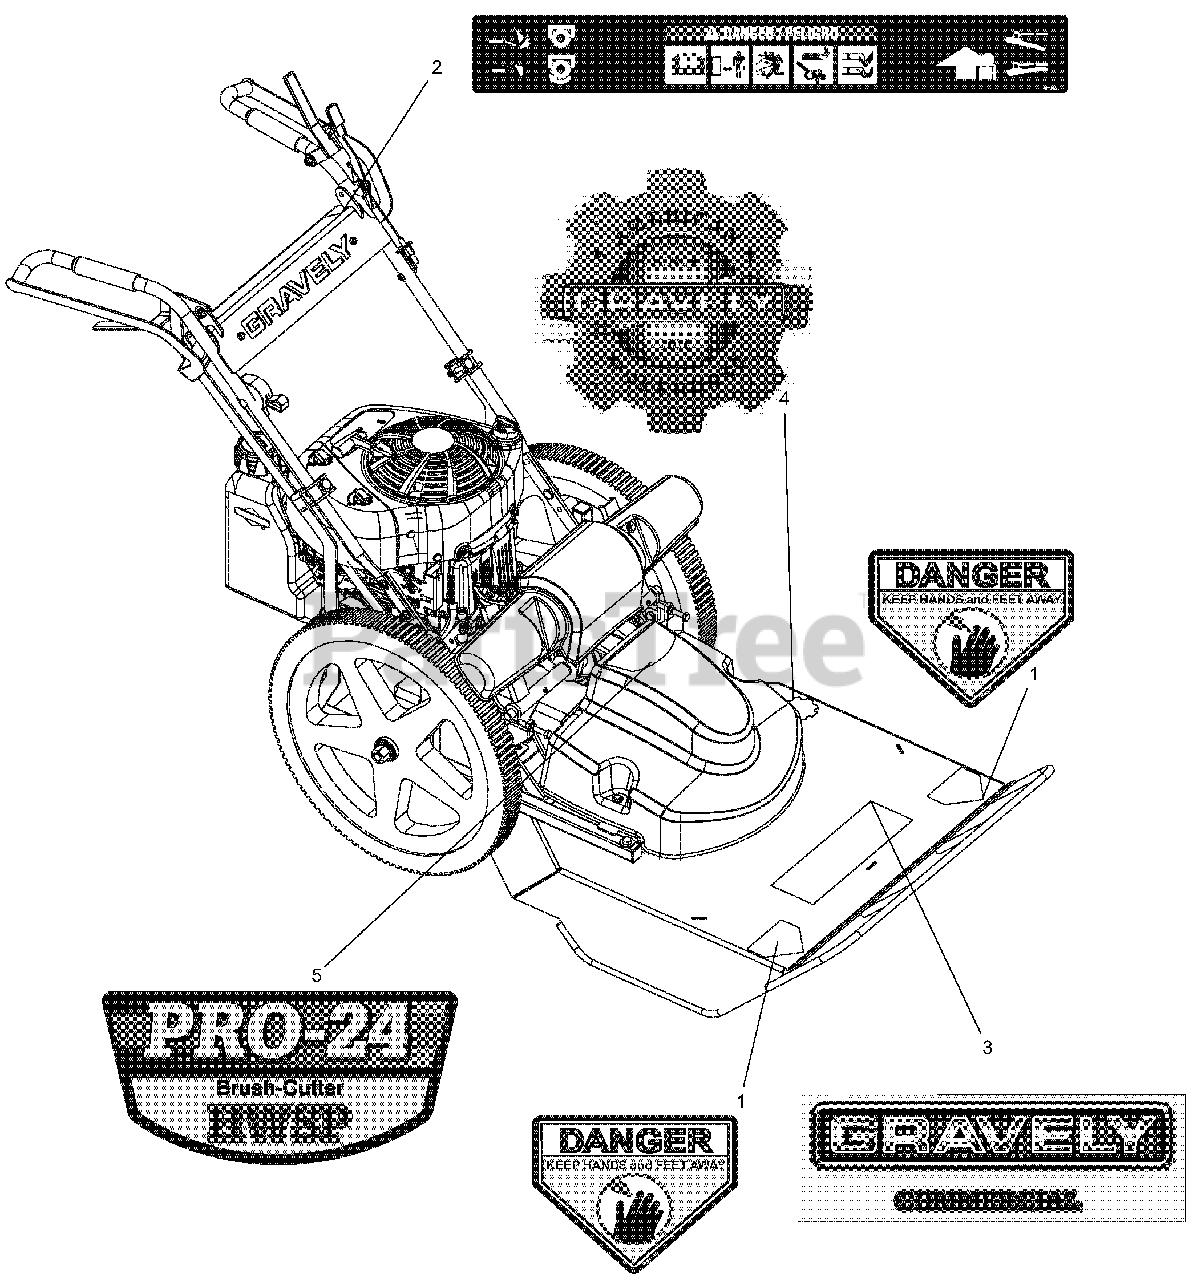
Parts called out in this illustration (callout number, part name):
1	DECAL, DANGER
2	DECAL-OPER./DANGER 24BRUSHCUT
3	DECAL, GRAVELY /COMMERCIAL LOGO
4	DECAL, GRAVELY HERITAGE-SMALL
5	DECAL, BRUSHCUTTER 24"
